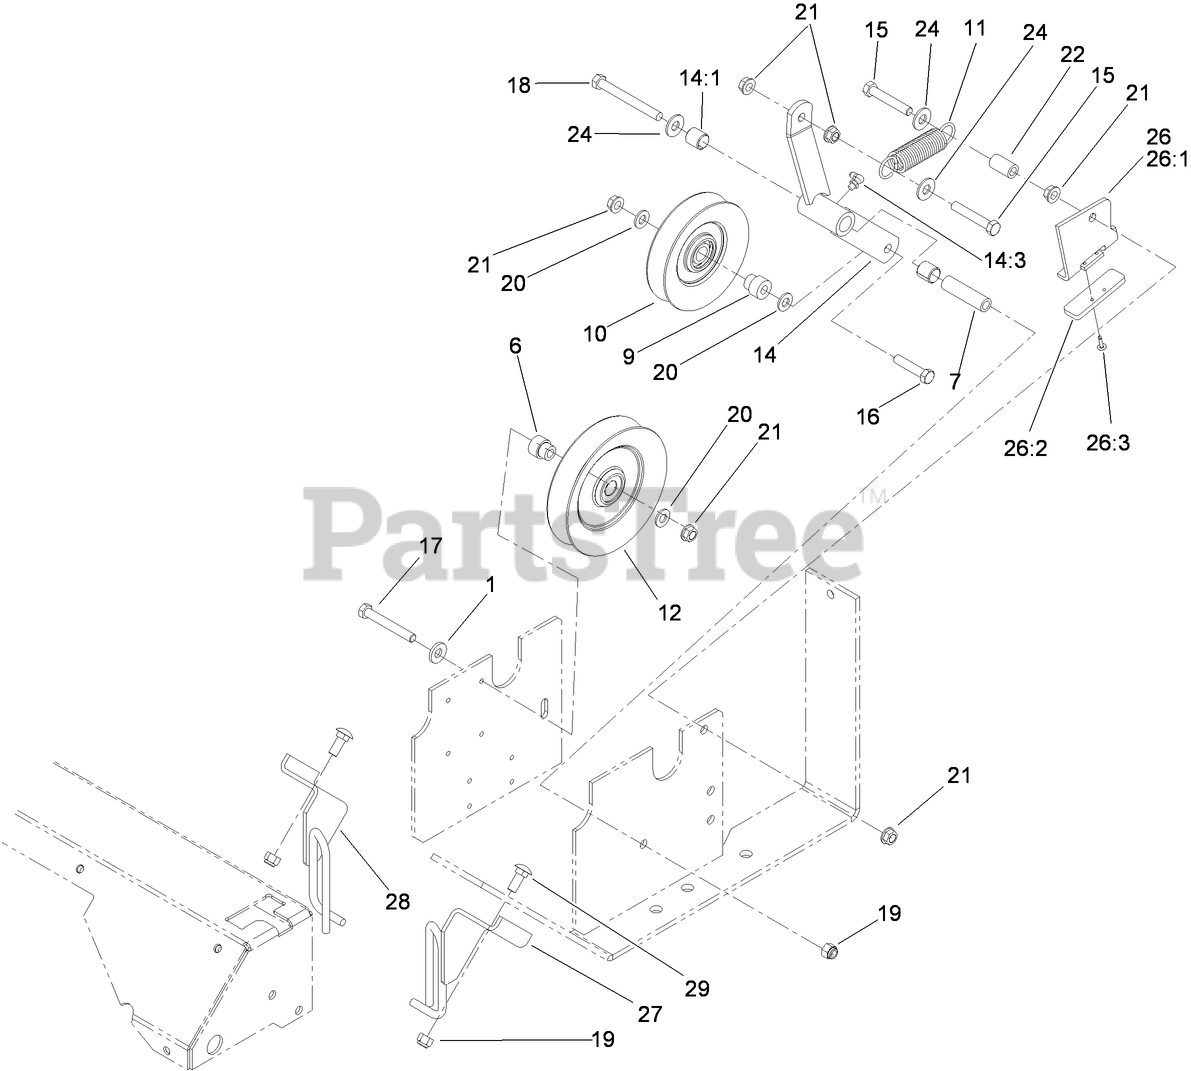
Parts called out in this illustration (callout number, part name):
1	WASHER-BELLEVILLE
6	Bushing-Idler
7	BUSHING-PIVOT, IDLER
9	BUSHING-IDLER
10	Idler
11	SPRING-EXTENSION
12	PULLEY-IDLER
14	Arm ASM
14:1	SLEEVE-BEARING
14:3	FITTING-GREASE, 90 DEG
15	SCREW-HH
16	SCREW-HH
17	SCREW-HH
18	SCREW-HH
19	NUT-LOCK, NI
20	WASHER-FLAT
21	NUT-HHF, WHIZ
22	SPACER
24	WASHER-FLAT
26	Travel Limiter ASM
26:1	Plate-Limiter, Pulley
26:2	PAD-BUMPER
26:3	RIVET
27	GUIDE-BELT, LH
28	GUIDE-BELT, RH
29	BOLT-CARR
